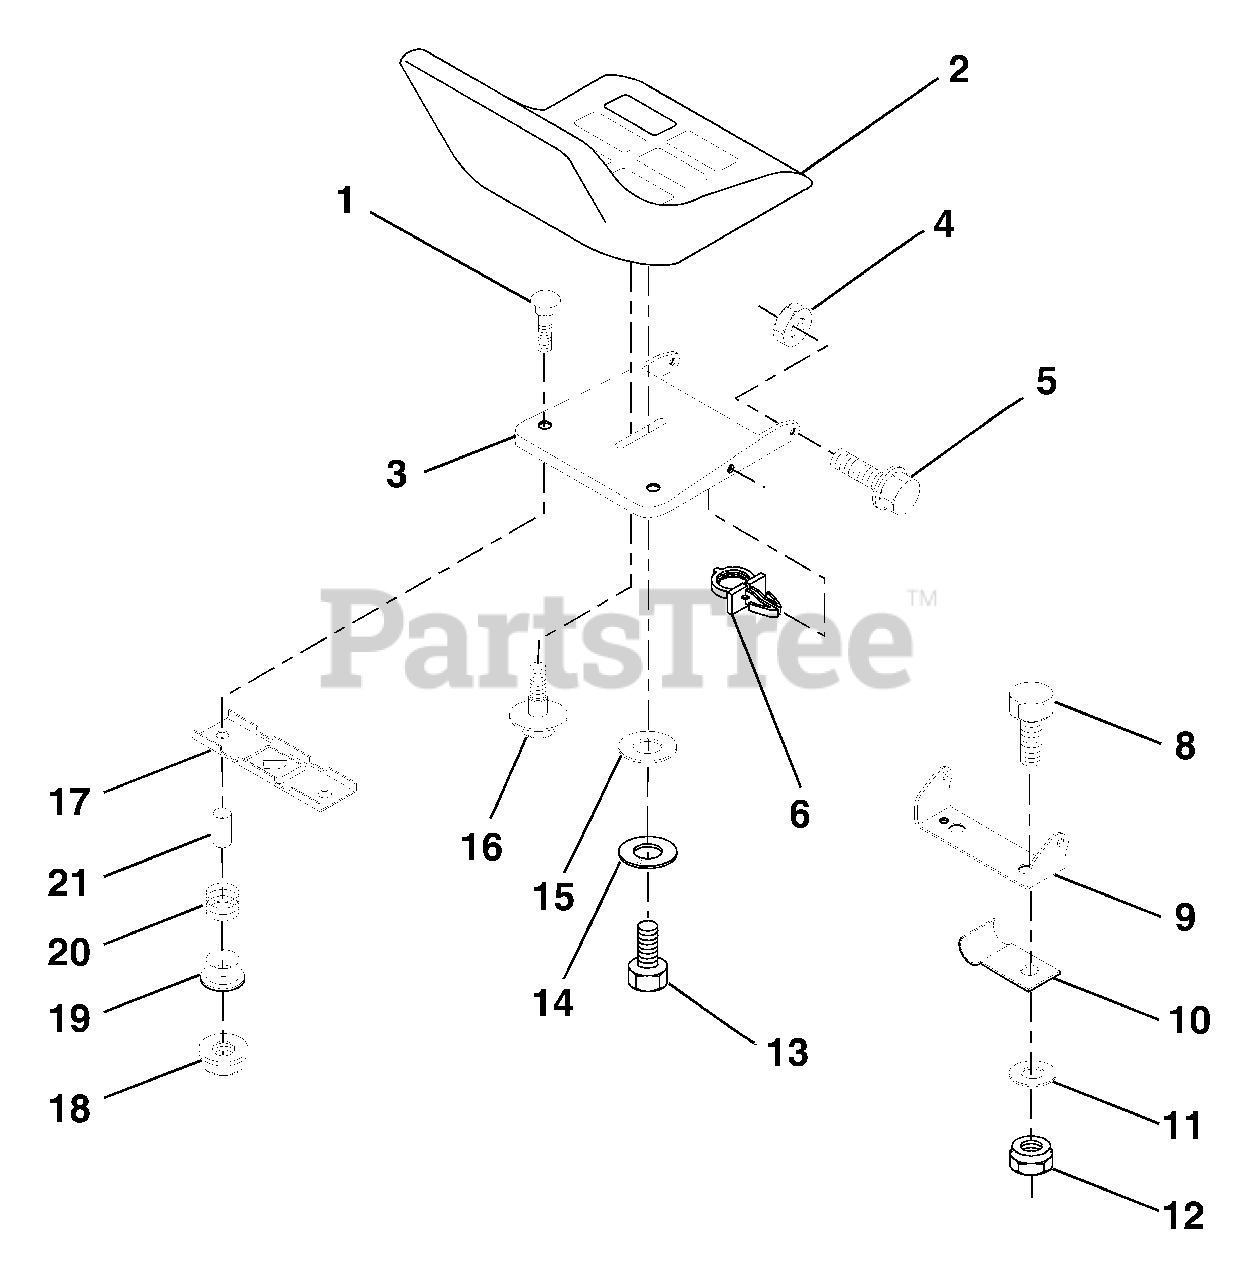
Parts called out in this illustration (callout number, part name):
1	Bolt, Carriage 1/4-20 x 1-3/8
2	Seat
3	Pan, Seat
4	Nut, Lock Hex w/Ins. 5/16-18
5	Bolt, Shoulder 5/16-18 UNC
6	Clip, Insulated
8	Bolt, Fin Hex 3/8-16 UNC x 1
9	Bracket, Pivot Seat
10	Clip, Insulated
11	Washer 12/32 x 2 x 10 Ga.
12	Nut, Lock Hex w/Wsh 3/8-16
13	Bolt, Hex 1/2-13 x 7/8
14	Washer, Lock Hvy. Hlicl Spring 1/2
15	Washer, 17/32 x 1-3/16 x 12 Ga.
16	Bolt, Shoulder
17	Bracket, Switch, Mounting
18	Nut, Hex Large Flange Lock
19	Bushing, Snap
20	Spring, Compression
21	Spacer, Split 28 Id. x .88 Lg.
